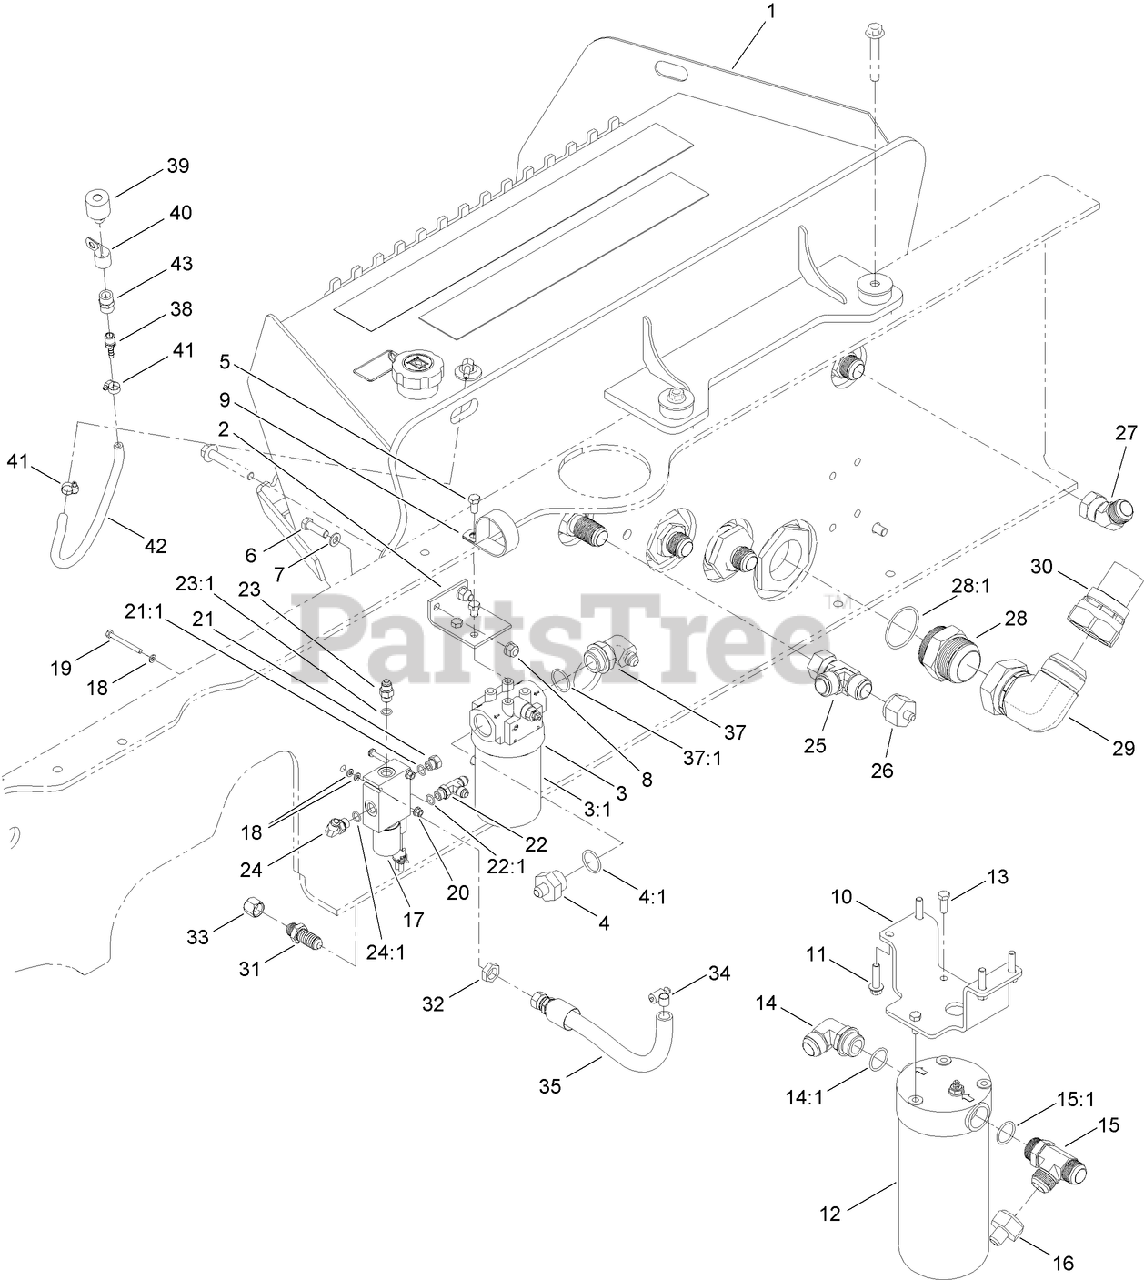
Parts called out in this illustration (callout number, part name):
1	HYD TANK ASM
2	BRACKET-MOUNTING, FILTER
3	OIL FILTER ASM
3:1	FILTER-HYD
4	CONNECTOR ASM
4:1	O-RING
5	SCREW-HH
6	Screw-HH
7	WASHER-FLAT
8	NUT-LOCK, NI
9	CLAMP-R
10	BRACKET-FILTER
11	SCREW-HHF
12	HYD RETURN FILTER ASM
13	SCREW-HH
14	ELBOW-90 DEG
14:1	O-RING
15	FITTING-TEE
15:1	O-RING
16	ADAPTER-REDUCER
17	SOLENOID VALVE ASM
18	WASHER-FLAT
19	SCREW-HH
20	NUT-FLANGE, NI
21	PLUG-HH
21:1	O-RING
22	FITTING-TEE
22:1	O-RING
23	FITTING-STRAIGHT
23:1	O-RING
24	FITTING-ELBOW, 90 DEG
24:1	O-RING
25	TEE-SWIVEL
26	REDUCER
27	FITTING-ELBOW, 45
28:1	O-RING(3-932)
29	ADAPTER-90 DEG
30	FITTING-STRAIGHT
32	NUT-LOCK
34	CLAMP-HOSE
35	HYD HOSE ASM, LP
37	FITTING-ELBOW, 90
37:1	O-RING
38	FITTING-STRAIGHT
39	BREATHER
40	CLAMP-R
41	CLAMP-WORM
42	HOSE-FUEL
43	COUPLING-PIPE (NPTF)
